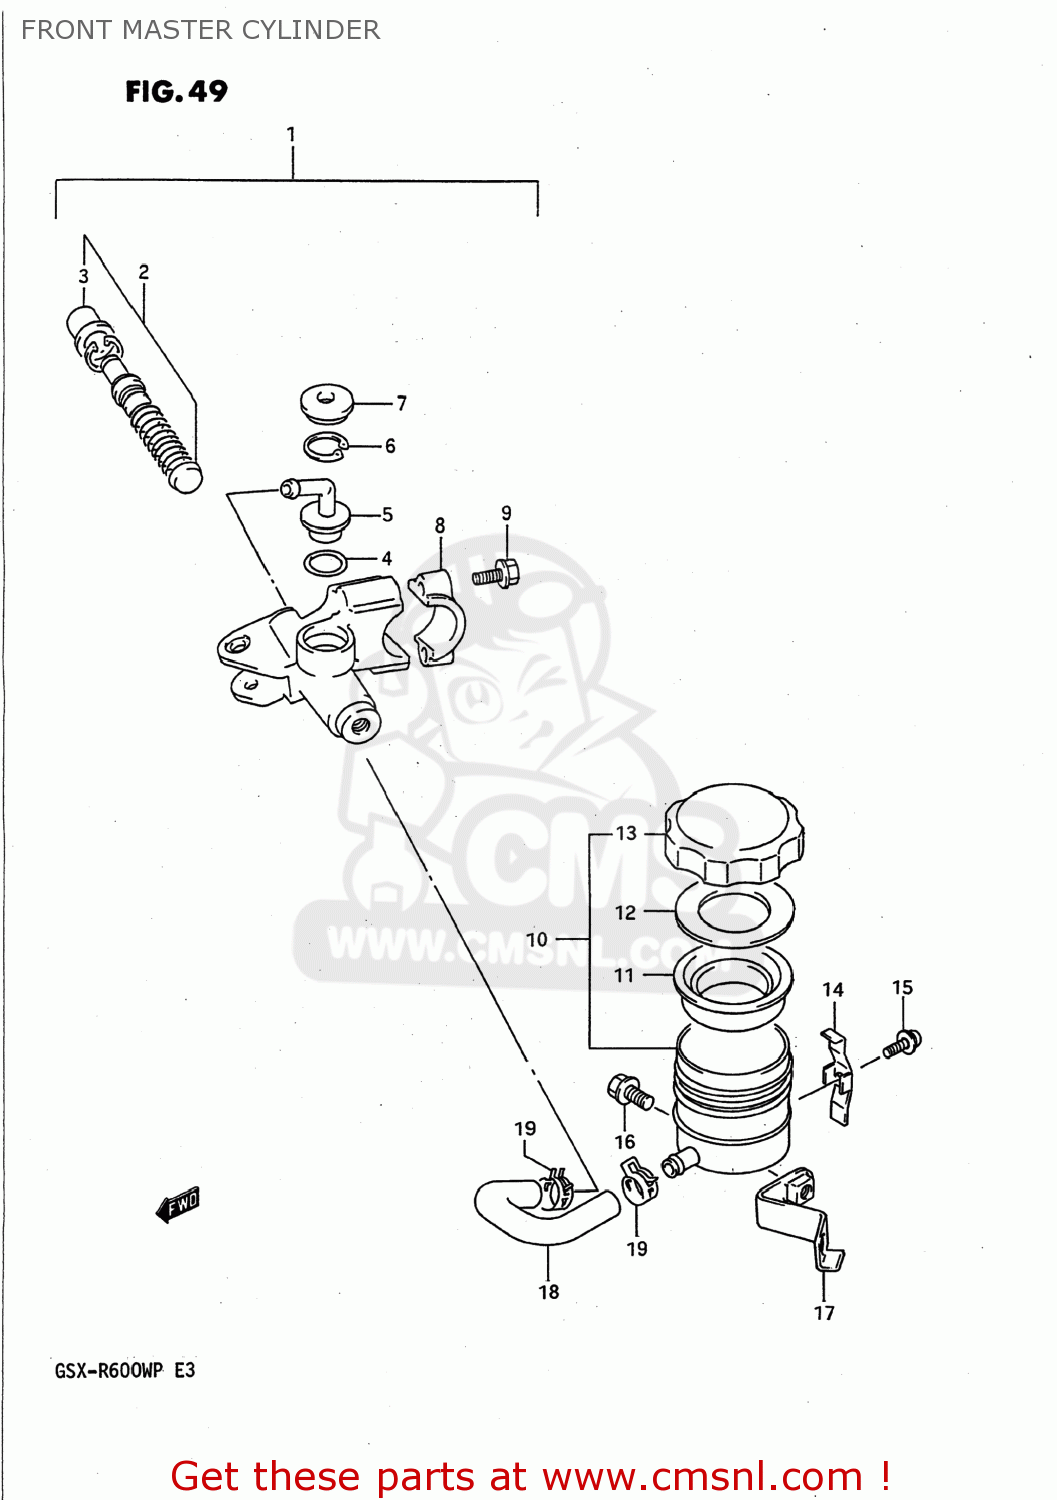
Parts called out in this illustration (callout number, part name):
1	CYLINDER ASSY,FR MASTER
2	PISTON & CUP SET
3	BOOT
4	O RING
5	CONNECTOR
6	CIRCLIP
7	COVER,DUST
8	HOLDER
9	BOLT(6X25)
10	TANK ASSY,RESERVOIR
11	DIAPHRAGM
12	PLATE,DIAPHRAGM
13	CAP
14	PLATE,RESERVOIR TANK CAP
15	SCREW
16	BOLT 6X16
17	BRACKET,RESERVOIR TANK
18	HOSE,RESERVOIR TANK FR
19	CLAMP,RESERVOIR TANK FR
